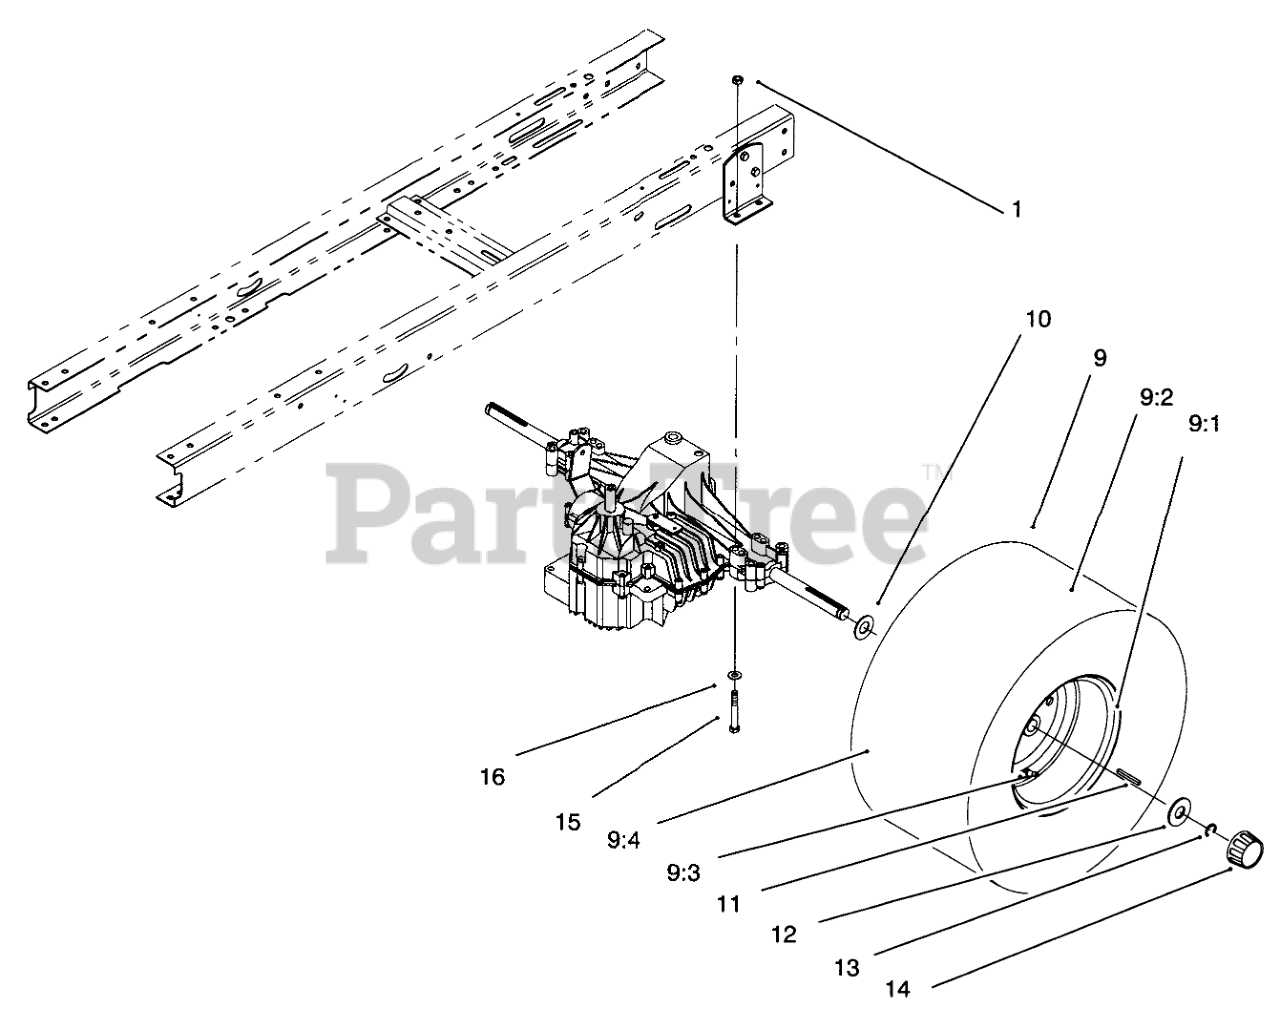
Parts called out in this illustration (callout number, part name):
1	NUT-LOCK, NI
9	Rear Wheel & Tire ASM (Incl. Ref. #9:1-9:4)
9:2	TIRE 18 X 9.50 X 8
9:3	STEM-VALVE
9:4	Tube
10	WASHER-THRUST
11	KEY-SQUARE
12	WASHER-PLAIN
13	E-RING
14	CAP-HUB
15	SCREW-HH
16	WASHER-PLAIN
